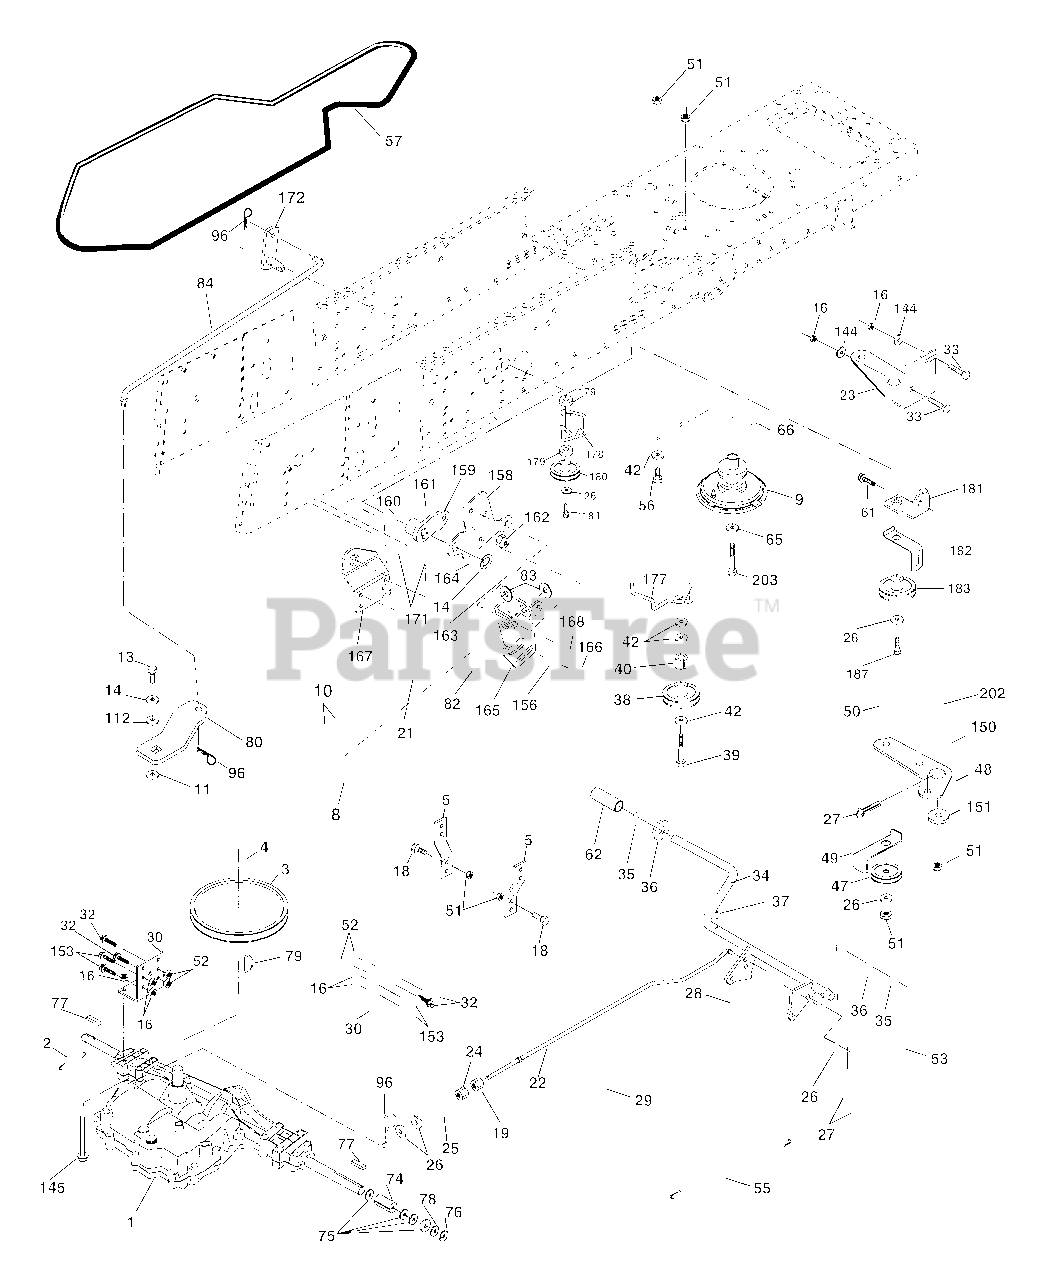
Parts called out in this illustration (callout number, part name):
2	Spring Brake Return
3	Pulley Transaxle
4	Ring Retainer #5100-62
5	Strap torque 30 degrees
8	Rod Shift Fender Adjust Lt
9	Clutch Asm Noram
10	Pin, Cotter 1/8 x 1
11	Washer Plate Shf .3888 sq hole
13	Bolt 1/4-28 Unf Gr 8 w/patch
14	Washer, Lock Hvy Helical
16	Nut, Lock Hex w/Ins 5/16-18 UNC
18	Bolt Hex 3/8-16 UNC x 1 Gr.5
19	Nut, Lock Hex w/Wsh 3/8-16 UNC
20	Bolt, Hex 7/16-20 x 4-1/4 5 Ga. 1.38
21	Knob Duckhead 1/2-13 Unc Blk
22	Rod, Brake CRD 0650
23	Bracket Asm Clutch Noram
24	Nut
25	Spring, Rod, Brake
26	Washer 13/32 x 13/16 x 16 Ga.
27	Pin, Cotter 1/8 x 3/4
28	Rod, Parking Brake
29	Cap, Parking Brake
30	Bracket, Mfg. Transaxle
32	Bolt Hex 5/16-18 UNC x 3/4
33	Bolt Rdhd Sqnk 5/16-18 Unc x 3/4
34	Shaft, Asm Pedal Foot CRD
35	Bearing, Nylon
36	Washer 21/32 x 1 x 16 Ga.
37	Pin, Roll 3/16 x 1"
38	Pulley, Flat
39	Bolt Rdhd 3/8-16 Unc x 2-3/4 Gr. 5
40	Spacer, Split 395 x 59 Bzp
42	Washer 13/32 x 13/16 x 12 Ga.
47	Pulley, Idler, V Groove Plasitc
48	Bellcrank Clutch Grnd Drv
49	Retainer, Belt Style Spring
50	Bolt Hex Hd 3/8-16 UNC x 1-1/2
51	Nut, Crownlock 3/8-16 UNC
52	Nut Crownlock 5/16-18
53	Link, Clutch 7.66
55	Spring, Return, Clutch
56	Bolt, Hex 3/8-16 UNC x 1-1/4
57	V-Belt Kev PMST CRD
61	Screw 3/8-16 x 3/4
62	Cover, Pedal
65	Washer
66	Keeper, Belt Engine F-Proof
74	Spacer Axle
75	Washer 25/32 x 1-1/4 x 16 Ga.
77	Key, Square
78	Washer 25/32 x 1-5/8 x 16 Ga.
79	Key Woodruff
80	Arm Shift PMST 20" Tires
82	Spring, Torsion
83	Washer 17/32 x 3/4 x 16 Ga.
84	Link Shift CRD Pmst 18" Tires
96	Spring, Retainer 1"
112	Washer 9/32 x 3/4 x 10 Ga.
145	Bolt Hex FGHD 5/16-18 x Gr 5
150	Bushing, Bellcrank Grnd Dr
151	Washer 13/32 x 2 x 10 Ga.
153	Bolt Hex Hd 5/16-18 Unc x 1
156	Washer Srred 5/16 ID x 1.125
158	Bracket Shift Mount
159	Hub Tapered Flange Shift Lt
161	Bolt Rdhd Sqnk 1/4-20 x 3/4 Gr 5
162	Nut Crownlock 1/4-20 Unc
163	Bolt Hex Fin 1/4-20 Unc x 1 Gr 5
164	Washer 5/8 x .281 x 10 Ga.
165	Bracket Pivot Lever
166	Screw 5/16-18 x 5/8
167	Bracket Support Shift CRD
168	Bolt Shoulder 5/16-18 x .561
171	Screw Thdrol 3/8-16 x 1/2 Ty-Tt
172	Shaft Asm Shift Front CRD PMST
177	Keeper Flat Idler 3.06" CRD
178	Keeper Belt Idler 1.88" CRD
179	Washer Sintered
180	Pulley Flat Composite 3.06"
181	Bracket Idler Ground Drive CRD
182	Keeper Belt 2.5" Od V-Idler CRD
183	Pulley V-Idler 2.50" Od CRD
184	Screw Hexwsh Thdrol 3/8-16 x 2-3/4
187	Screw Thdrol 3/8-16 x 1-1/4
198	Washer Nyl 7/8 ID x .105" Hyd CRD
202	Bolt Carr Sh 3/8-16 x 1-1/2 Gr. 5
203	Bolt Hex 7/16-20 x 5
